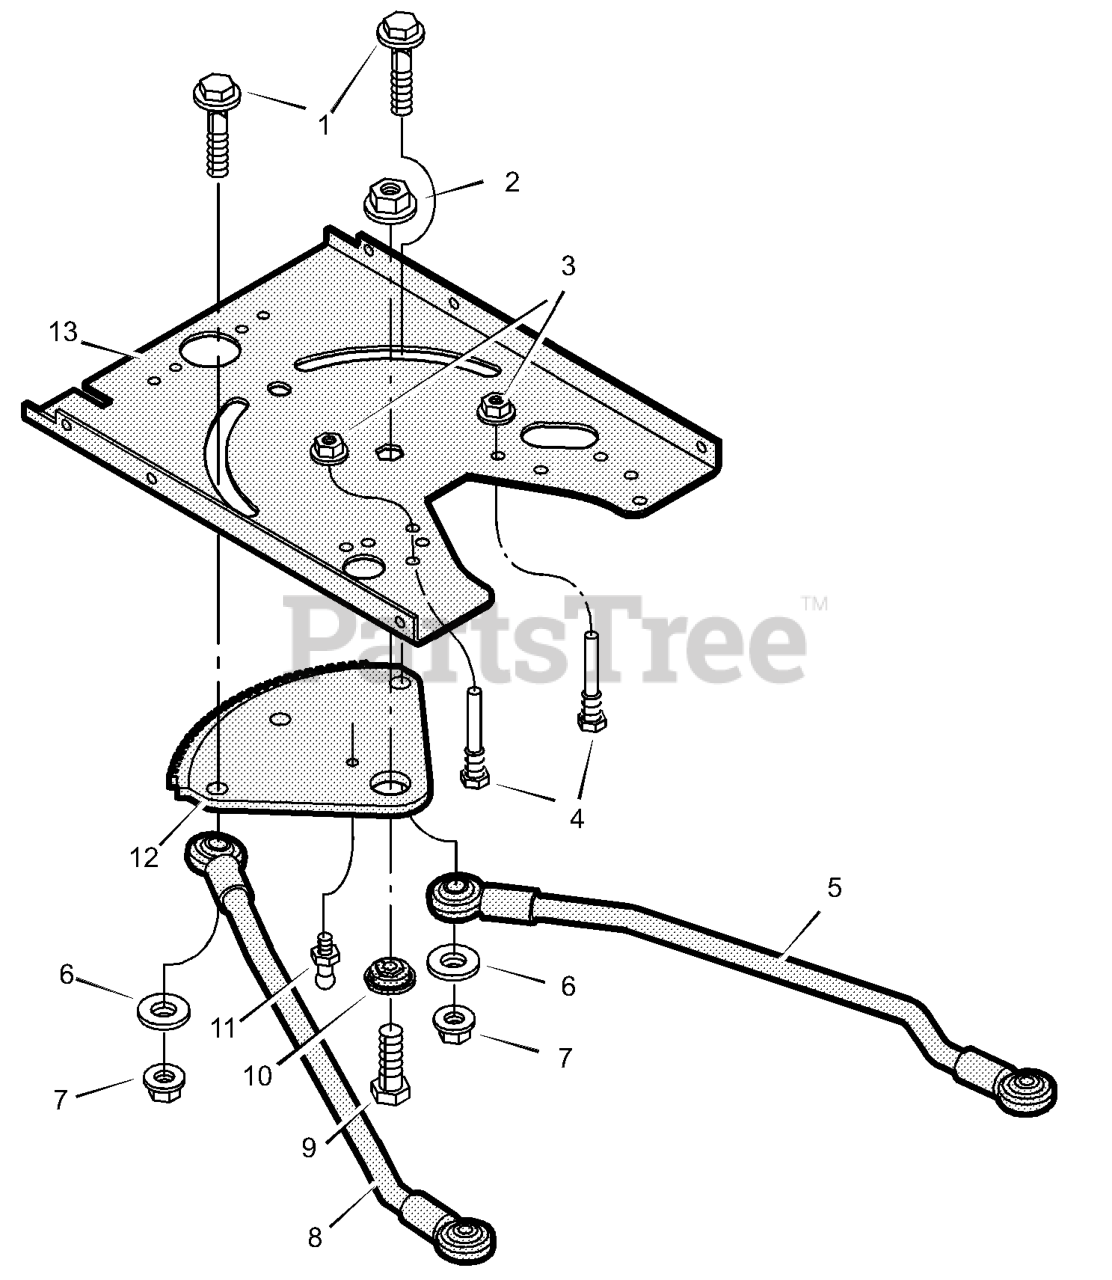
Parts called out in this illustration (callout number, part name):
1	Bolt, Shoulder
2	Nut, Lock
3	Nut, Flange
4	Guide, Screw
5	Link, Left Drag
7	Nut, Flange
8	Link, Right Drag
9	CAPSCREW, Hex Head, 5/16-18 x 1
10	Bearing, Sector Gear
11	Fitting, Lub
12	Gear, Sector
13	Plate, Steering
